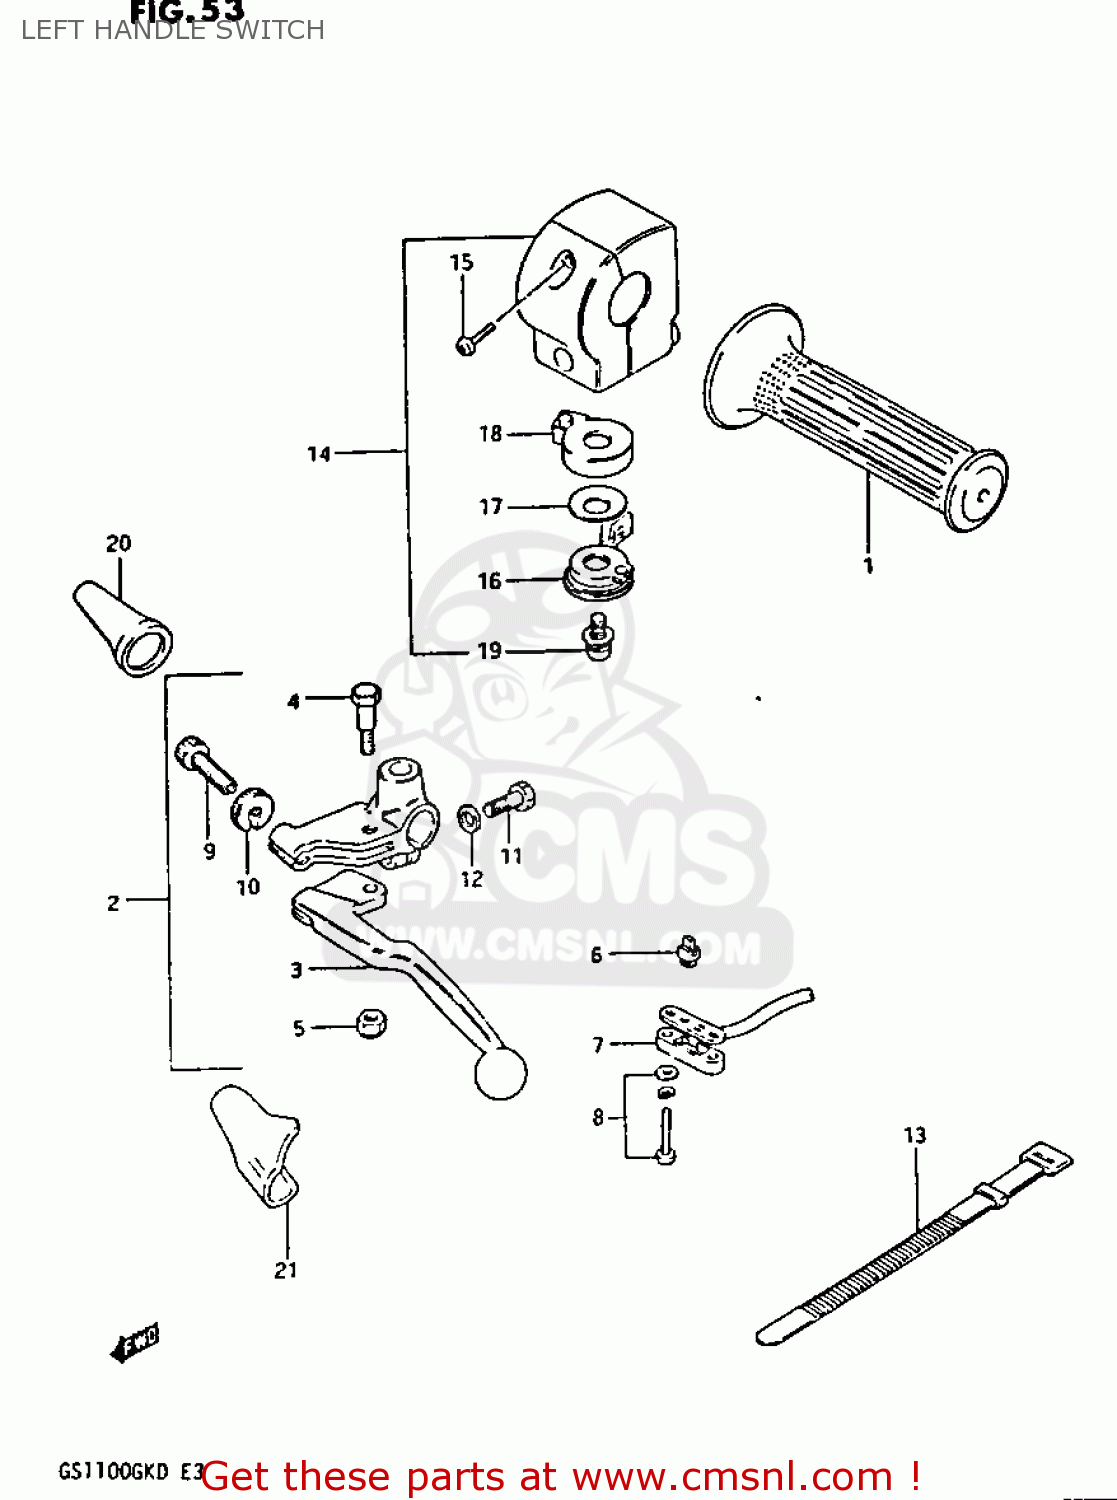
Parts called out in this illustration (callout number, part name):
1	GRIP,L
2	LEVER ASSEMBLY
3	LEVER,CLUTCH
4	BOLT,LEVER PIVOT
5	NUT 6MM
6	CONTACT,SWITCH
7	COVER,FR BK TERMINAL BASE
8	SCREW
9	ADJUSTER,CABLE
10	NUT,CABLE ADJUSTER
11	BOLT
12	WASHER
13	CLAMP(L:120)
14	SWITCH ASSY,HANDLE,L
15	SCREW
16	LEVER,STARTER
17	WASHER,ADJUSTER
18	BODY,STARTER LEVER
19	SCREW,CHOKE LE
20	BOOT,CLUTCH CABLE
21	COVER,CLUTCH LEVER
